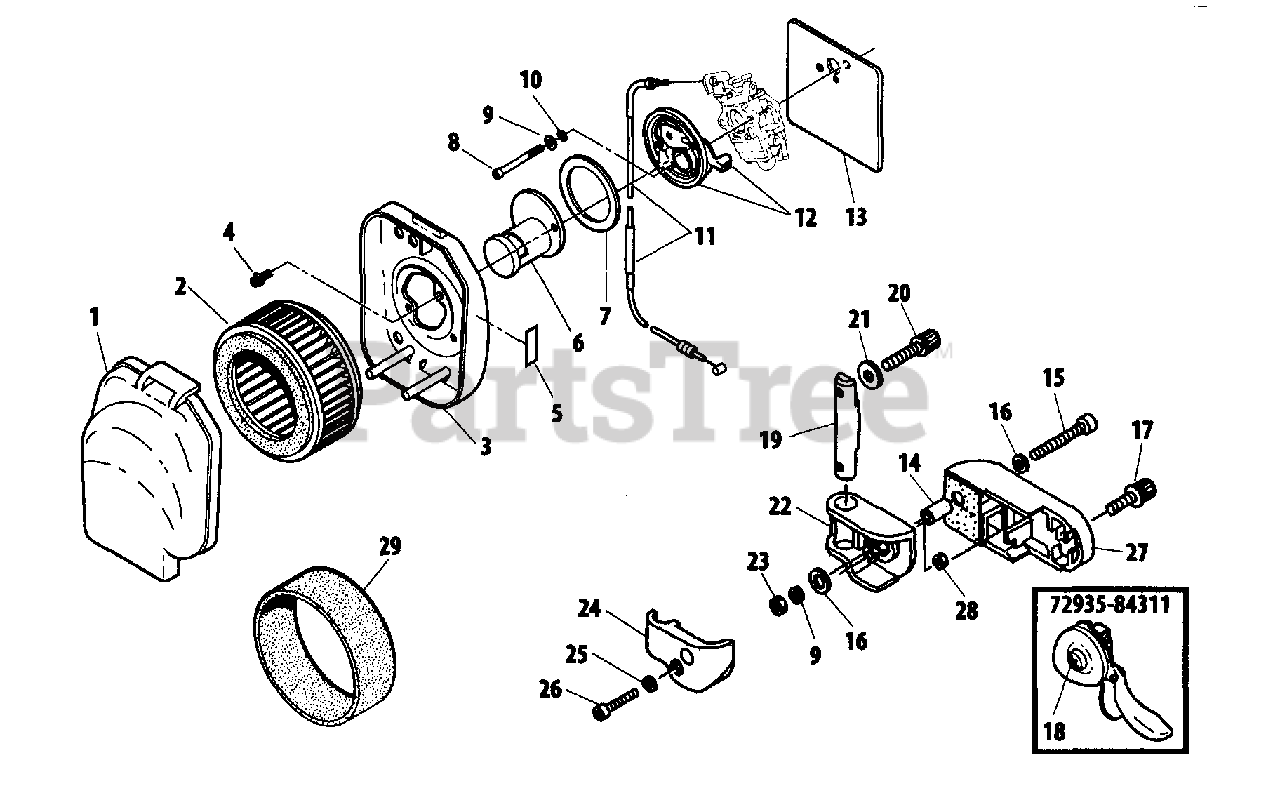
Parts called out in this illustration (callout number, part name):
1	COVER, AIR FILTER
2	FILTER, AIR
3	CASE, AIR FILTER
4	BOLT M4×14
5	LABEL, CHOKE
6	PIPE, INTAKE
7	GASKET, INTAKE
8	BOLT 5×60
9	WASHER, SPRING 5
10	WASHER, FLAT 5.5×10×0.8
11	CABLE, THROTTLE
12	CHOKE ASSY
13	GASKET, INTAKE
14	COLLAR
15	BOLT 5×25
16	WASHER
18	SCREW
20	BOLT M6×16
21	COLLAR Ø18ר6.4×L2
22	BRACKET, SWIVEL
23	NUT M5
24	COVER
25	WASHER 4 MM
26	BOLT, ADHESIVE M4×20
27	BRACKET, THROTTLE LEVER
28	NUT M4
29	PRE-FILTER
72935-84311	TRIGGER ASSY, THROTTLE
